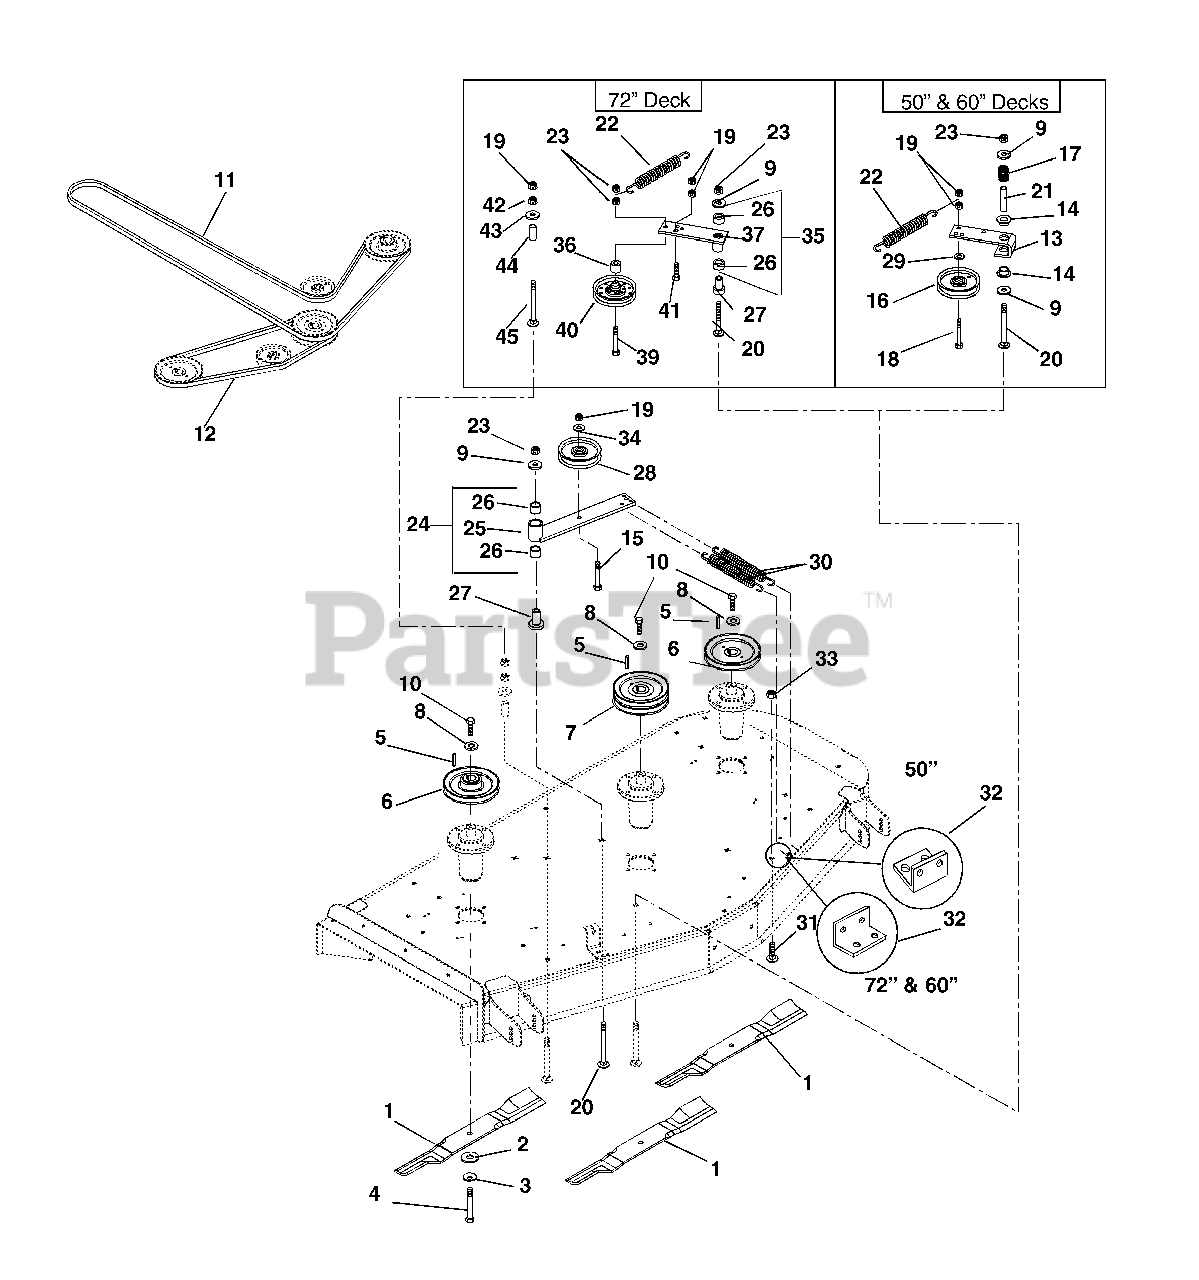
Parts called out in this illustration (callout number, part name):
1	Blade, 72" Mower Tungsten Hi-Lift
1	Blade, 60" Mower Tungsten Hi-Lift
1	Blade, 50" Mower Tungsten Hi-Lift
1	Blade, 50" Mower Sand Tungsten
1	Blade, 50" Mulching Tungsten
1	Blade, 60" Mulching Tungsten
1	Blade, 72" Mulching Tungsten
2	Washer, Flat .640 x 1.81 x .250
3	Washer-Bellville .63 x 1.625 x .14
4	Bolt, Blade
5	Key-Straight .25 x 1.00 x .25
6	Weldment, Spindle Sheave 7.00 (72" Deck)
6	Weldment, Spindle Sheave 6.00 (60" Deck)
6	Weldment, Spindle Sheave 5.00 (50" Deck)
7	Weldment, Sheave (Double) 7.25 (72" Deck)
7	Weldment, Spindle Sheave (Double) 6.25 (60" Deck)
7	Weldment, Spindle Sheave (Double) 5.25 (50" Deck)
8	Washer, Cupped, Serrated .375
9	Washer-Flat-Steel .531 x 1.25 x .100
10	Bolt-Hex .38-16 x 1.00 Grade 8
11	V-Belt, B-RMA 69.81 x .625 (72" Deck)
11	V-Belt, B-RMA 63.40 x .625 (60" Deck)
11	V-Belt, B-RMA 58.70 x .625 (50" Deck)
12	V-Belt, B-RMA 28.62 x .625 (72" Deck)
12	V-Belt, B-RMA 23.94 x .625 (60" Deck)
12	V-Belt, B-RMA 18.13 x .625 (50" Deck)
13	Arm,Idler Pivot
14	Bushing-Flange-Nylon .762 x 1.0 x .580 x 1.48
15	Bolt, Hex .38-16 x 3.00 Grade 5
16	Idler-V 4.00 x .377
17	Spring-Compression .085 x .80 x 1.00
18	Bolt-Hex .38-16 x 2.25 Grade 5
19	Nut-Locking-Center .38-16 (50" & 60" Decks)
19	Nut-Locking-Center .38-16 (72" Decks)
20	Bolt-Round Head Square Neck .50-13 x 3.50
21	Spacer .560 x .750 x 2.437 Steel
22	Spring, Extension
23	Nut-Locking-Center .50-13
24	Assembly, Idler Pivot Arm
25	Weldment, Idler Pivot Arm
26	Bearing, 1.00 x 1.12 x .75
27	Bearing, Pedistal Powdered Metal
28	Idler-Flat 4.00 x .38 (2.00 W)
29	Bushing .406 x .750 x .188
30	Spring, Extension
31	Bolt-Round Head Square Neck .38-16 x 1.00 Grade 5
32	Bracket, Spring
33	Nut-Locking-Nylon .38-16
34	Washer-Flat-Steel .375 x 1.125 x .065
35	Assembly, Idler Arm-Ground Drive
36	Spacer .51 x .75 x .62
37	Weldment, Idler Arm Ground Drive
38	Bolt-Round Head Square Neck .50-13 x 3.50 G5
39	Bolt-Hex .50-13 x 2.50 Grade 5
40	Idler-Flat-Pulley 6.75 x .510
41	Bolt-Hex .38-16 x 1.25 Grade 5
42	Nut-Locking-Nylon .38-16
43	Washer-Flat-Steel .406 x .812 x .065
44	Spacer .380 x .625 x 1.50
45	Bolt-Round Head Square Neck .38-16 x 2.75 Grade 5
